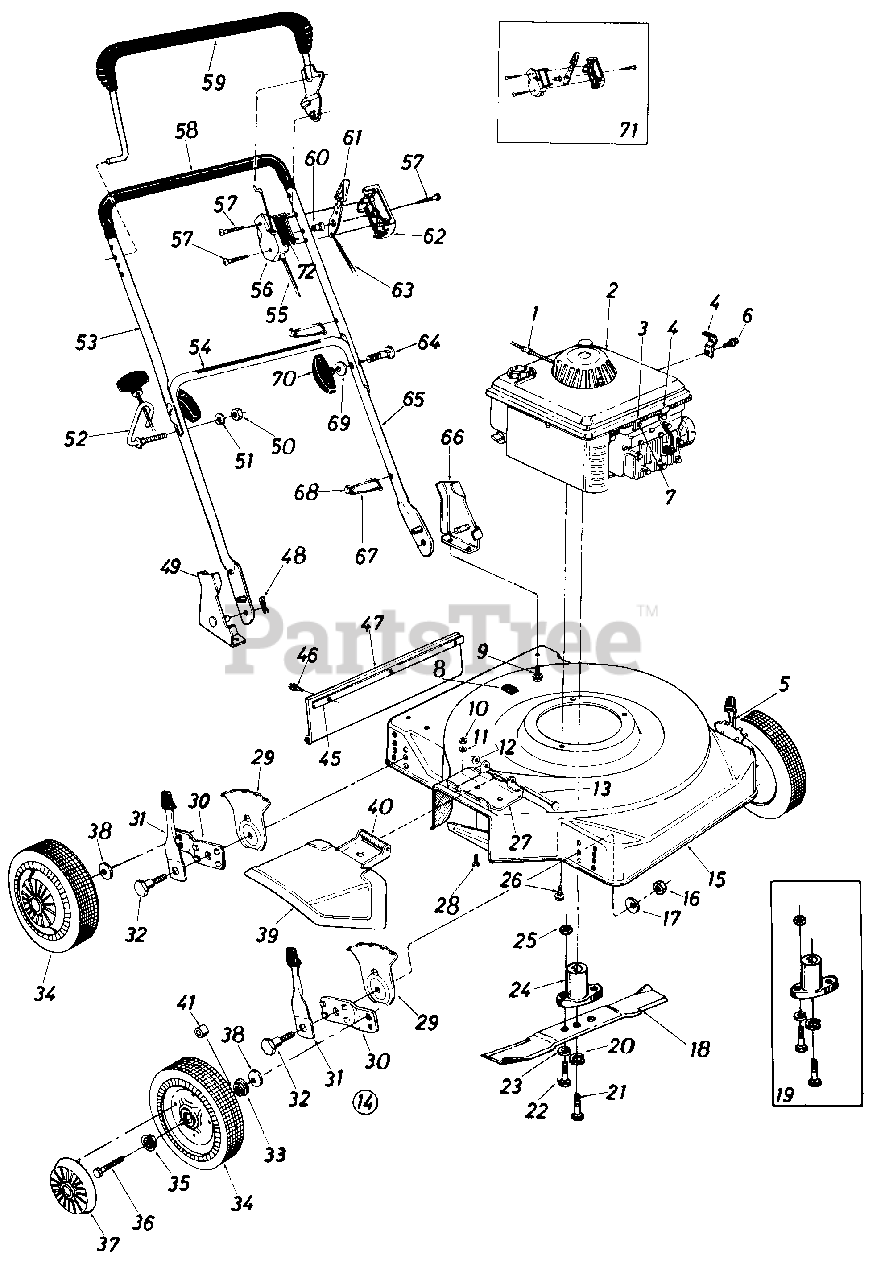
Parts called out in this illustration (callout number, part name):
1	Stop Clip
2	Engine
3	Casing Clamp
4	Throttle Control Cable Clip
5	Height Adj. Ass'y.-L.H.
6	Hex "B" Tap Scr. #10 x .38"
7	Hex "B" Tap Scr. #10 x .62"
8	Plastic Plug
9	Hex Wash. Hd. "B"-Tap Scr. 5/16-18 x .50" Lg.
10	Hex Nut 1/4-20 Thd.
11	L-Wash. 1/4" I.D.
12	Push Cap .25" Rod
13	Hinge Pin 1/4" Dia. x 3.88" Lg.
14	Height Adj. Ass'y.-R.H.
15	20" Deck Ass'y.
17	Bell-Wash. .39" I.D. x 1.4" O.D.
18	20" Blade
19	Blade Adapter Kit
20	L-Wash. 3/8" I.D.-H.D.
21	Hex Bolt 3/8-24 x 2.25" Lg. (Grade 5)
22	Hex Bolt 5/16-24 x 1.00" Lg. (Grade 5)
23	L-Wash. 5/16" I.D.
24	Blade Adapter
25	Hex Nut 5/16-24 Thd.
26	Hex Wash. Hd. TT-Tap Scr. 3/8-16 x 1.00" Lg.
27	Deflector Hinge Plate
28	Hex Bolt 1/4-20 x .50" Lg.
29	Index Plate-Front
30	Wheel Pivot Bar-Front
31	Spring Lever With Knob
32	Shoulder Bolt .500" Dia. x .430
33	Ball Brg.-1/2" I.D.
34	Wheel Ass'y. Comp. 8.0 x 1.75
35	Ball Brg.-3/8" I.D.
36	Axle Bolt
37	Hub Cap-Black Plastic
38	Bell-Wash. .400" I.D. x .88" O.D.
39	Chute Deflector Ass'y. Comp.
40	Torsion Spring
41	Spacer
45	Retainer Strip
46	Hex AB-Tap Scr. 1/4 x .62" Lg.
47	Rear Flap Ass'y. 4.65 x 17.2" Lg.
48	Intern Cotter Pln 5/16" Dia.
49	Handle Mount Brkt. Ass'y.-R.H.
50	Hex Nut 5/16-18 Thd.
51	L-Wash. 5/16" I.D.
52	Rope Guide Bolt
53	Upper Handle
54	Instruction Label-Handle
55	43" Control Cable-Yellow
56	Clutch Panel Half
57	Truss Mach. H1-B Tap Scr. #12 x 1.50" Lg.
58	Grip-Handle-22" Lg.
59	Control Handle Ass'y.
60	Control Disc Pin
61	Throttle Control Lever
62	Control Panel Half
63	Throttle Control Wire 58" Lg.-Black
64	Curved Hd. Carr. Bolt 5/16-18 x 1.75" Lg.
65	Lower Handle
66	Handle Mount Brkt. Ass'y-L.H.
67	Cable Tie
68	Cable Anchor
69	Bell-Wash. .345" I.D. x .88" O.D.
70	Hand Knob
71	Throttle Control Housing-Comp.
72	Throttle Control-Label
